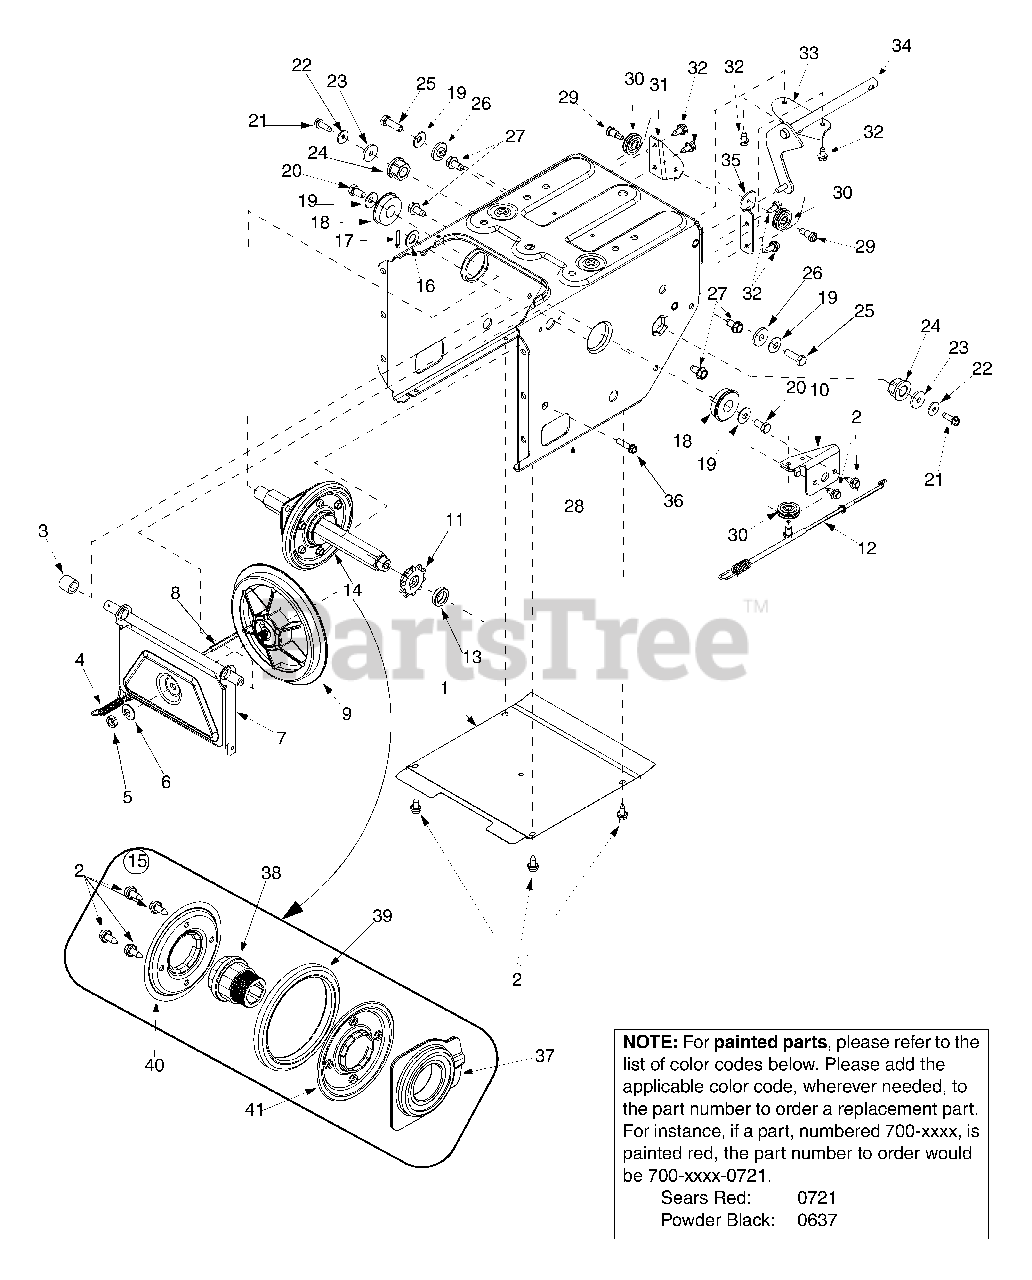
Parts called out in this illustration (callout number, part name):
3	Spacer
4	Extension Spring
5	Jam Nut 3/8-24
6	Bell Washer
9	Friction Disc
12	Auger Cable
13	Spacer
14	Hex Track Shaft
15	Friction Wheel Assembly, Complete
16	Flat Washer
17	Cotter Pin
18	Ball Bearing
19	Bell Washer
20	Hex Cap Screw 5/16-18 x.625
21	Tap Screw 1/4-20 x.75
22	Bell Washer.265 ID x.75 OD
23	Flat Washer 1/4 ID x.93 OD
24	Hex Flange Bearing
25	Hex Cap Screw 5/16-18 x 1"
26	Shoulder Spacer
27	Tap Screw 5/16-18 x.625
29	Hex Screw 1/4-28 x.375
30	Cable Roller
37	Friction Wheel Bearing
38	Friction Wheel Hub
39	Friction Wheel Rubber
40	Friction Plate
41	Friction Plate
